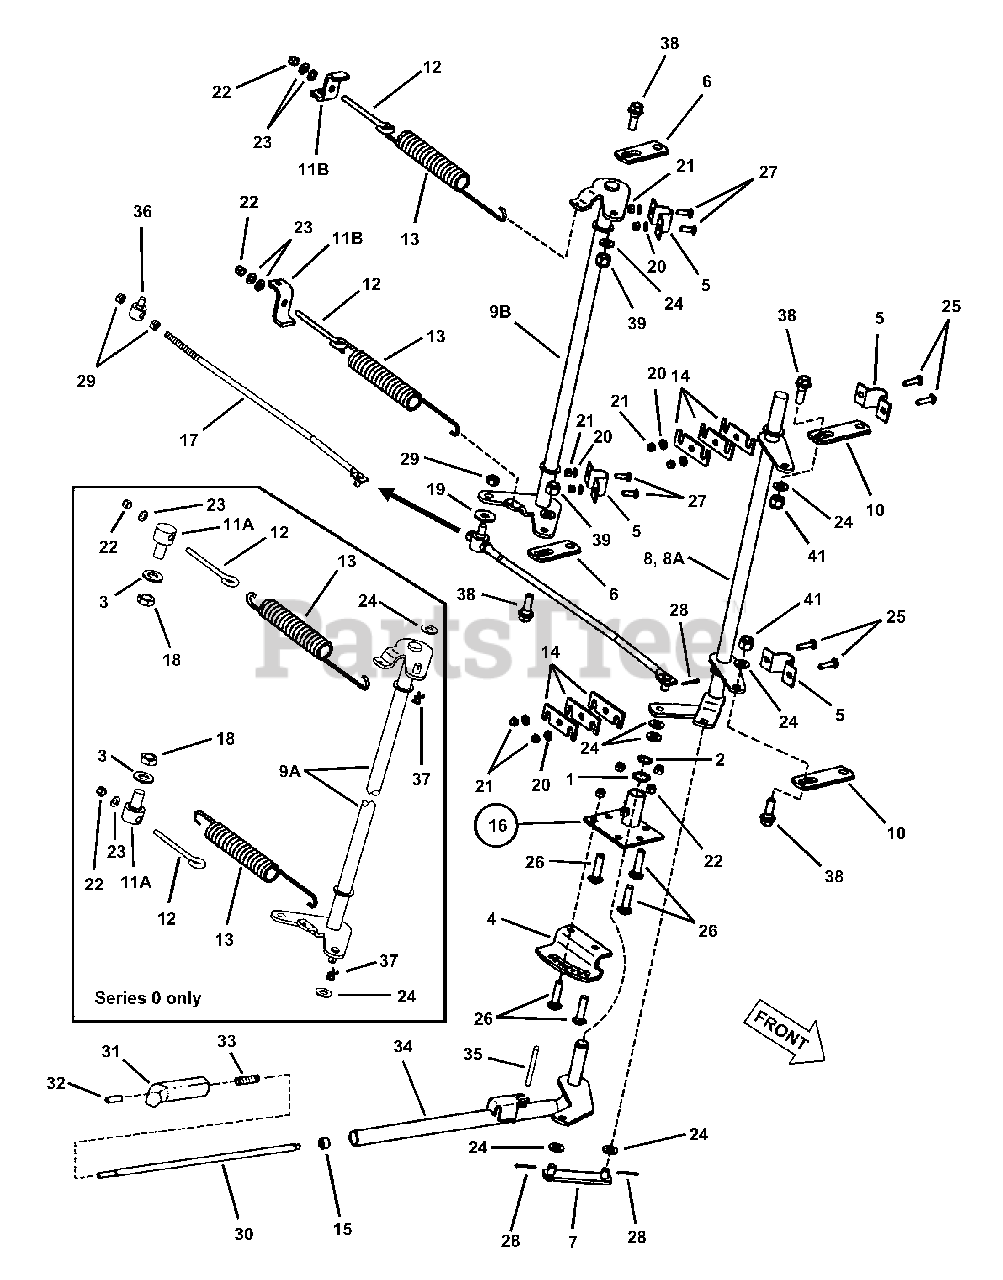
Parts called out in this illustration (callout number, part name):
1	WASHER, 29/32" I.D. x 1-1/4" O.D.
2	RING, 7/8" External Retaining
3	WASHER, 25/32" x 1-1/2" Flat (ZM Series 0 Models Only)
4	BRACKET, Deck Height Quadrant
5	BRACKET, Deck Support
6	PLATE, Rear Link (4.95" long) (ZM Series 0 Models Only)
7	WELDMENT, Lift Handle Link
8	LIFT, Front Deck (ZM Series 0 Models Only)
8A	LIFT, Front Deck (ZMT, MZM & ZM Series 1 Models)
9A	WELDMENT, Shaft Deck Lift (ZM Series 0 Models Only)
9B	WELDMENT, Shaft Deck Lift (ZMT, MZM & ZM Series 1 & 2 Models)
10	PLATE, Front Link (5.45" long) (ZM Series 0, 1 & 2 & ZMT Models)
11A	SWIVEL, Spring Anchor (ZM Series 0 Models Only)
11B	BRACKET, Spring Adjustment (ZMT, MZM & ZM Series 1 & 2 Models)
12	EYEBOLT, 5/16-18 x 3"
13	SPRING, Extension Lift Assist
14	PLATE, Shim
15	PLUG, Rod
16	ASSEMBLY, Pivot Plate
17	WELDMENT, Timing Rod
18	NUT, 3/4-16 Hex Jam Lock
19	WASHER, 17/32" x 1-1/2"
20	WASHER, 11/32" x 11/16" Flat
21	NUT, 5/16-18 HEX NYLON LOCK
22	NUT, 3/8-16 HEX NYLON LOCK
23	WASHER, 3/8" Flat
24	WASHER, 17/32" x 1-1/16"
25	BOLT, 5/16-18 x 1-1/2" Carriage Grade 5
26	BOLT, 3/8-16 x 1" Carriage
27	BOLT, 5/16-18 x 1-1/2" Carriage Grade 5
28	PIN, 1/8" x 1-1/4" Cotter
29	NUT, 1/2-13 HEX SIDE LOCK
30	ROD, Lift Lever
31	GRIP, Lift Lever Handle
32	CAP, Lift Rod
34	WELDMENT, Deck Lift Lever
35	PIN, 1/4" x 2-1/4" Groove
36	SWIVEL, Timing Rod
37	PIN, 1/8 x 1/2" Hair
38	BOLT, 1/2-20 Shoulder (ZMT, ZM & MZM Series 1 & 2 Models)
39	NUT, 1/2-20 Hex Jam (ZMT & ZM Series 1 Models)
41	NUT, 1/2-20 Hex Nyloc
